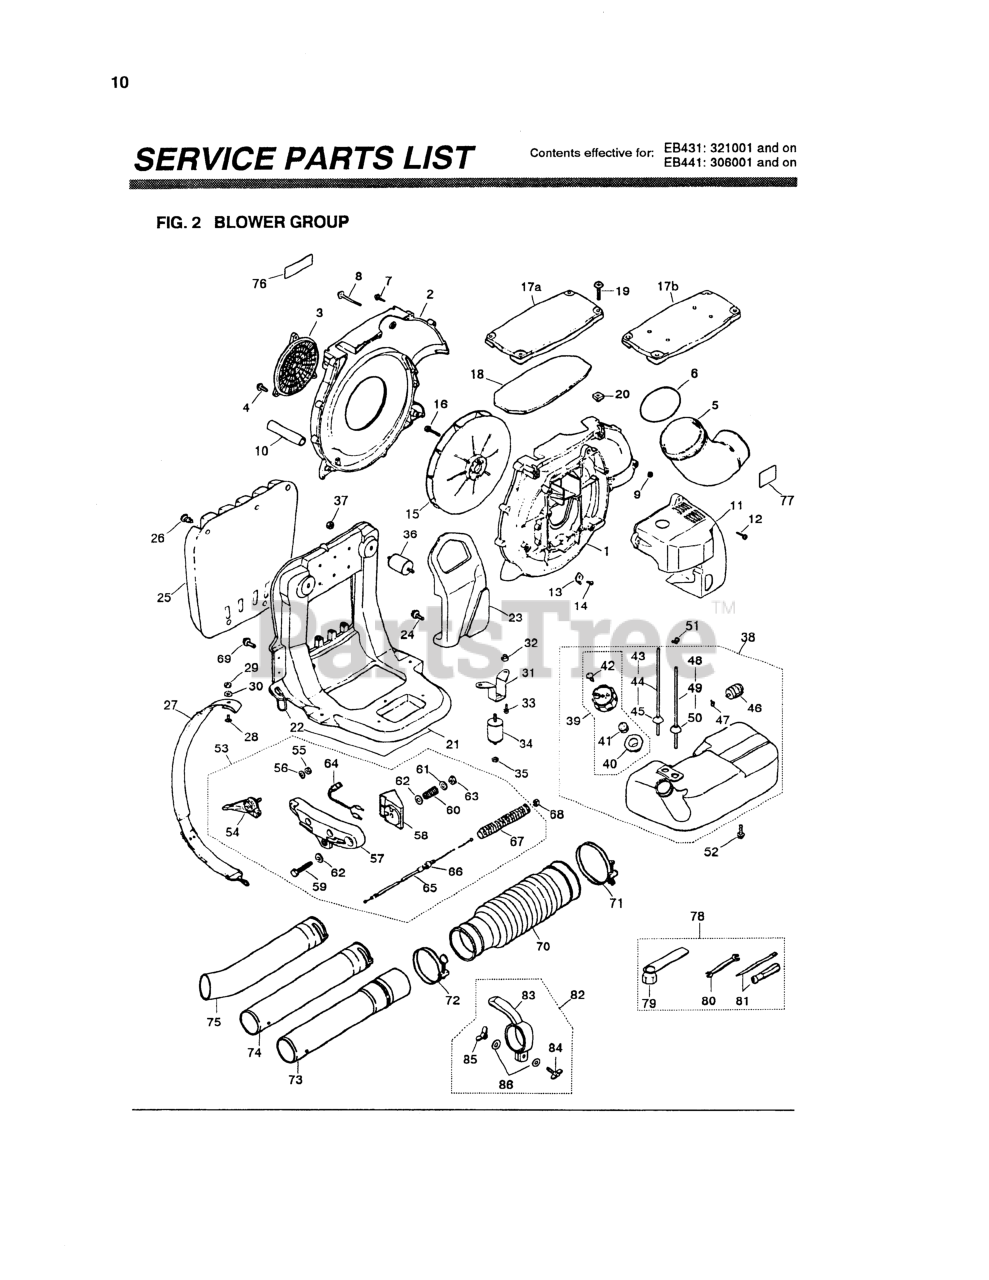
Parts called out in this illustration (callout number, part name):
2	COVER, VOLUTE (RPLS -11124)
3	NET, GUARD (RPLS-12222)
4	SCREW (RPLS -16120)
6	O-RING
7	SCREW
9	NUT (B)
15	FAN (REPLACES 3490-12110)
18	COVER, PACKING
19	SCREW
20	NUT
22	RING (USE -21121)
25	PAD (RPLS -21310)
26	CLIP (RPLS 3490-21320)
27	STRAP ASSY (NLA, USE -21411)
28	(NO LONGER AVAILABLE)
29	NUT, M6 X 5
31	BRACKET (RPLS -22510)
32	WASHER
33	SCREW, M5 X 20
35	NUT, M6 X 5
37	NUT, M6 X 5
43	PIPE (RPLS 3490-23410)
44	PIPE (USE 1696-85400)
45	GROMMET
46	FILTER ASSY
47	CLIP (REPLACES 2841-31280)
48	PIPE ASSEMBLY
49	PIPE (USE 1620-81710)
50	GROMMET
51	CLIP
53	LEVER (EB441)
54	LEVER, THROTTLE
55	NUT (B)
56	WASHER, M5x.8(RPLS 01624-20508
58	BRACKET
59	BOLT
60	SPRING
61	WASHER
62	WASHER, PLANE(USE 01640-20816)
63	NUT, M6 X 5
64	SWITCH, STOP
65	CABLE COMP,THROTTLE EB441
66	NUT, M6 X 5
67	TUBE (USE 5548-73310)
68	NUT, M6 X 5
69	BOLT
70	HOSE, FLEXIBLE
71	2756-51510 (RPLS. 07280-09832)
73	JOINT, SWIVEL
74	PIPE, EXTENSION
75	PIPE, BENT
78	TOOL SET (RPLS-91000)
80	SPANNER, 8 X 10 (RPLS 2540- )
81	SCREWDRIVER
82	BLOWER ASSIST HANDLE
83	EBH100
84	BOLT, WING
85	NUT, WING
86	WASHER
